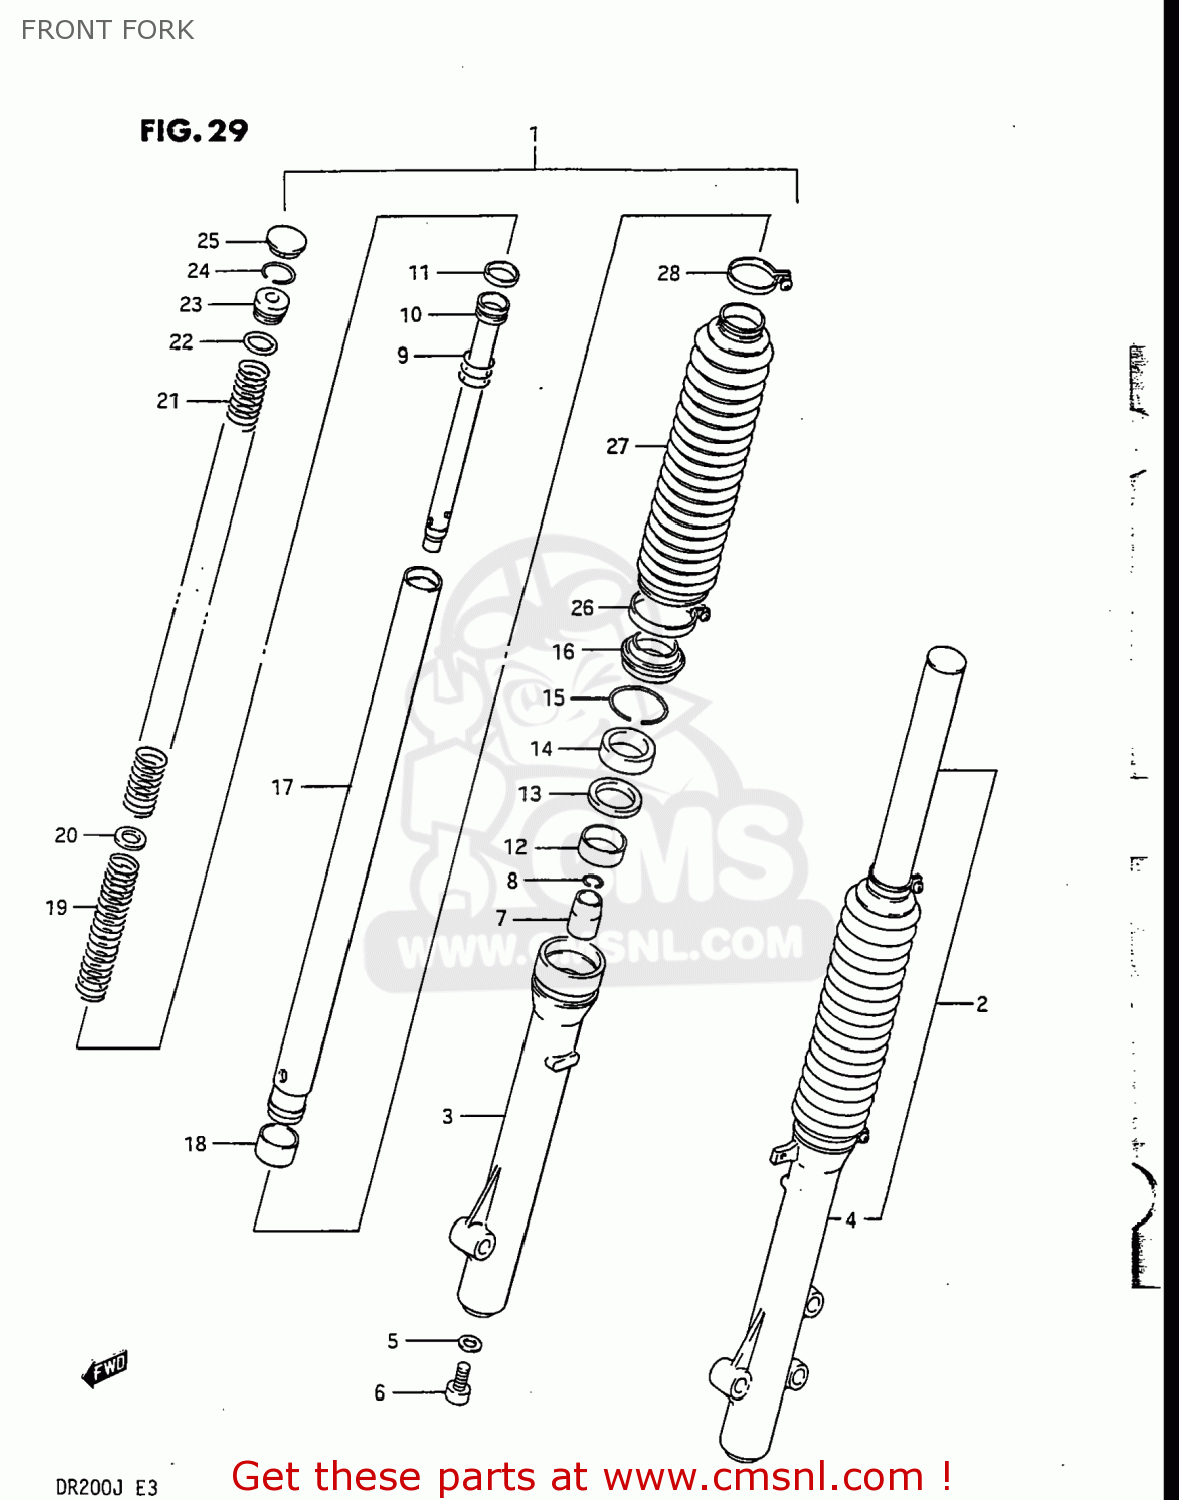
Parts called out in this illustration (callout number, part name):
1	DAMPER ASSEMBLY,RIGHT
2	DAMPER ASSEMBLY,LEFT
3	TUBE,OUTER,RIGHT
4	TUBE,OUTER,LEFT
5	GASKET (NAS)
6	BOLT(8X27)
7	PIECE,OIL LOCK
8	RING,STOPPER
9	SPRING,REBOUND
10	CYLINDER
11	RING,PISTON
12	BUSH,GUIDE
13	SPACER,SEAL
14	OIL SEAL,FRONT FORK
15	CIRCLIP,FORK OIL SEAL
16	SEAL,DUST
17	TUBE,INNER
18	PISTON
19	SPRING,LWR
20	SPRING,JOINT
21	SPRING,UPR
22	O RING
23	SPRING SEAT B
24	RING,STOPPER
25	CAP
26	BAND
27	BOOT
28	BAND
